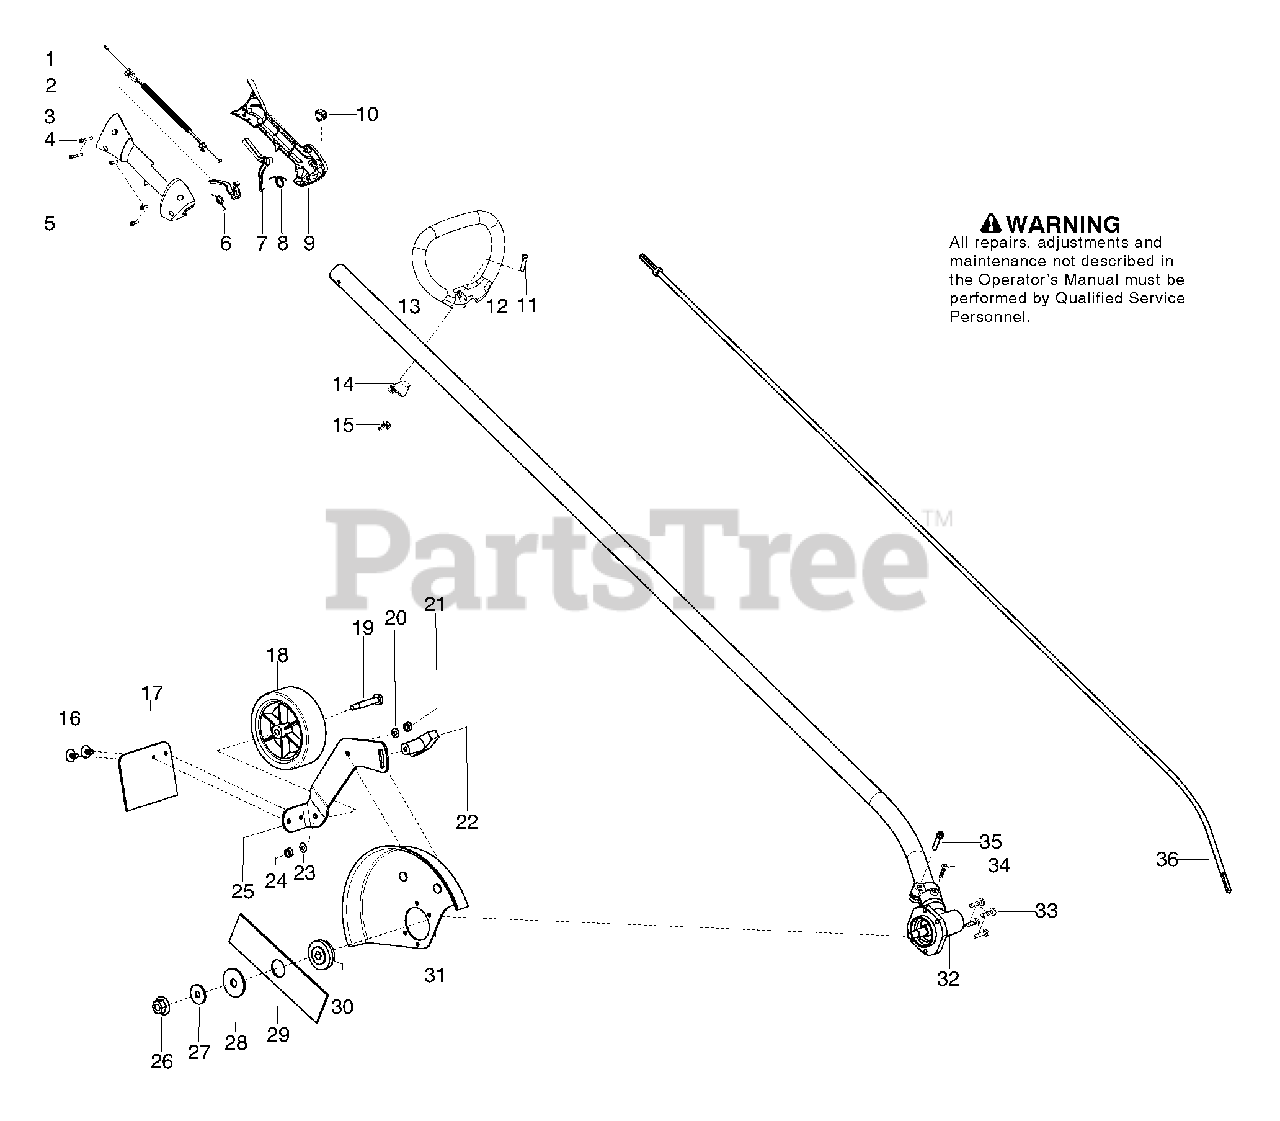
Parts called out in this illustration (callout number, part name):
1	Assy-Cable/Wire Harness
2	Trigger
3	Housing-Throttle (RH)
6	Spring-Trigger
7	Lockout-Throttle
8	Spring-Lockout
9	Housing-Throttle (LH)
10	Kit-Switch
12	Handle-Assist
13	Kit-Driveshaft Edger
14	Clamp-Handle
15	Wingnut
16	Fastener - Mud Flap
17	Kit-Mud Flap
18	Wheel - 4"
19	Bolt-Shoulder Axle
25	Bracket-Wheel Adjustment
26	Nut-Flange L.H.
27	Washer-Belleville Spring
28	Washer-Flat
31	Kit-Edger Guard
32	Kit-Edger Gearbox
34	Screw (align)
